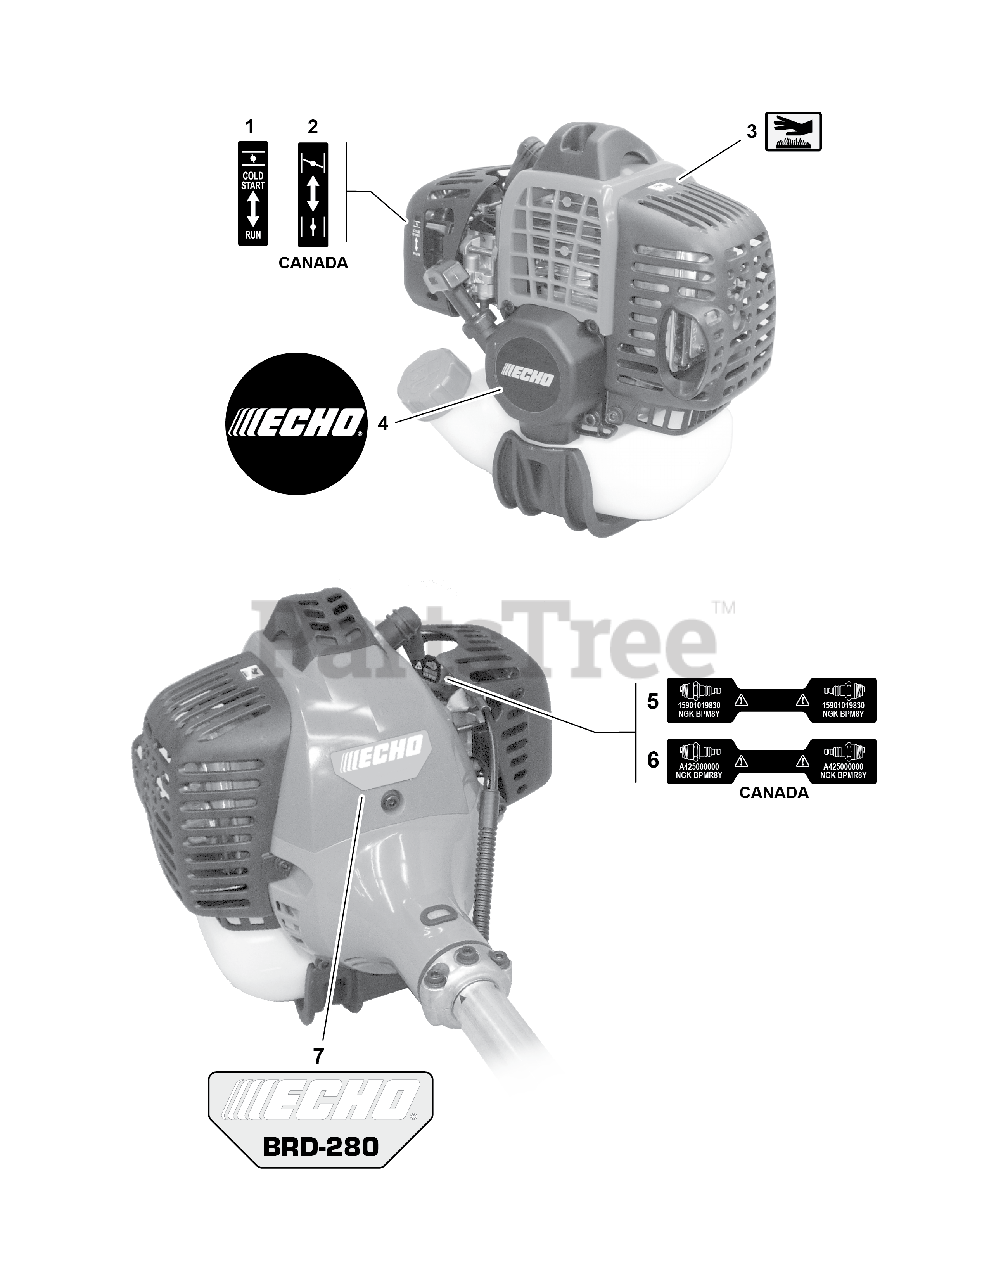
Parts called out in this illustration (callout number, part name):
1	LABEL - CHOKE
2	LABEL - CHOKE
3	LABEL - CAUTION --HOT
4	LABEL - ECHO
5	LABEL - SPARK PLUG -- BPM8Y
6	LABEL - SPARK PLUG -- BPMR8Y
7	LABEL - MODEL -- BRD-280
